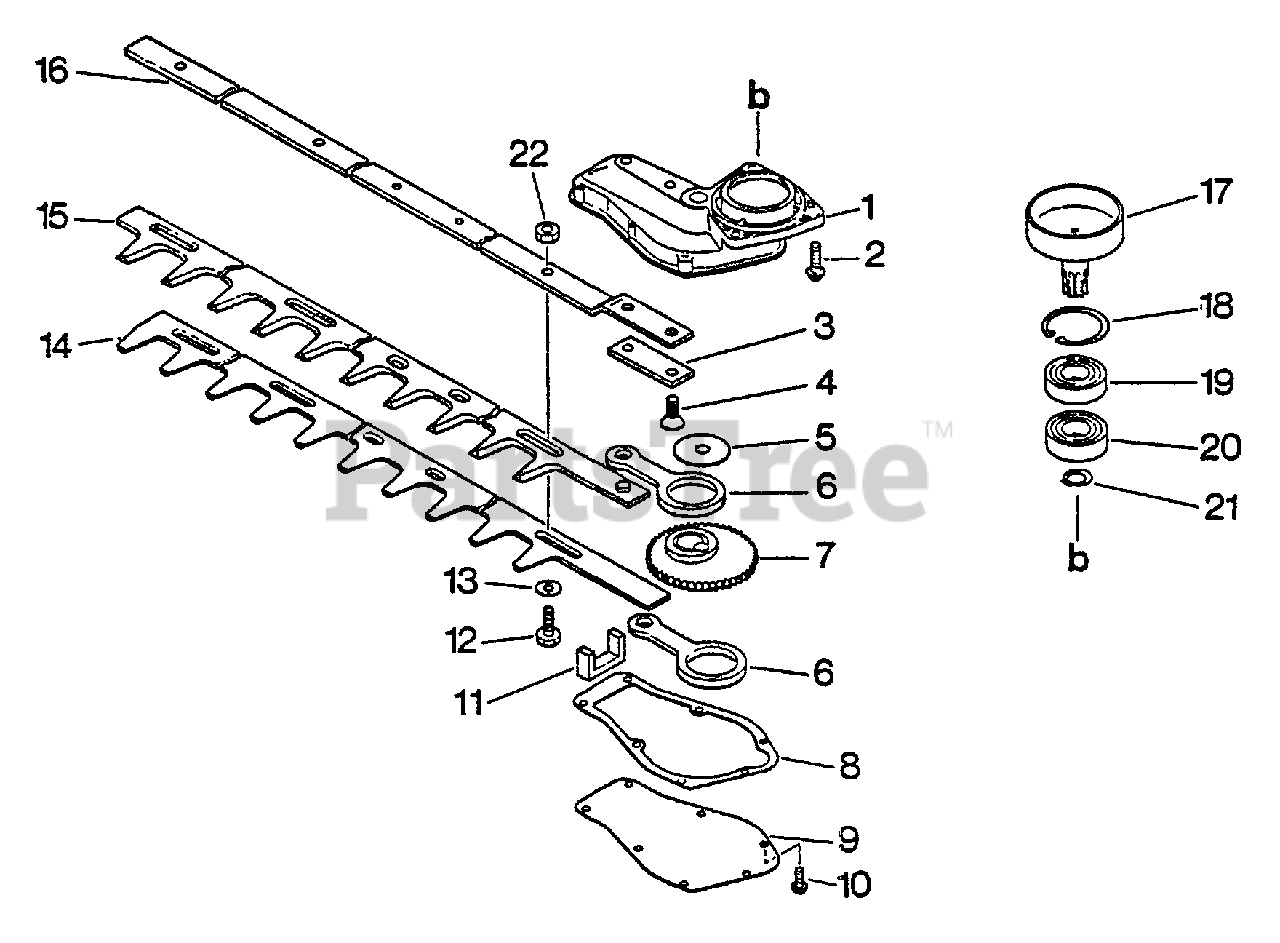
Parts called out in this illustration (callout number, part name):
1	CASE, GEAR
2	SCREW 5×20
3	PLATE, EYE
4	SCREW 6×18
6	ROD, CONNECTING
8	GASKET, GEAR CASE
9	LID, GEAR CASE
10	SCREW 4×10
12	BOLT, CUTTER
13	WASHER 6.5×15.5×0.6
14	CUTTER, LOWER
15	CUTTER, UPPER
16	BAR, FRAME
17	DRUM, CLUTCH
18	RING, SNAP 35
19	BEARING, BALL 6202
20	BEARING, BALL 6202
21	RING, SNAP 14
22	LOCKNUT - 6
